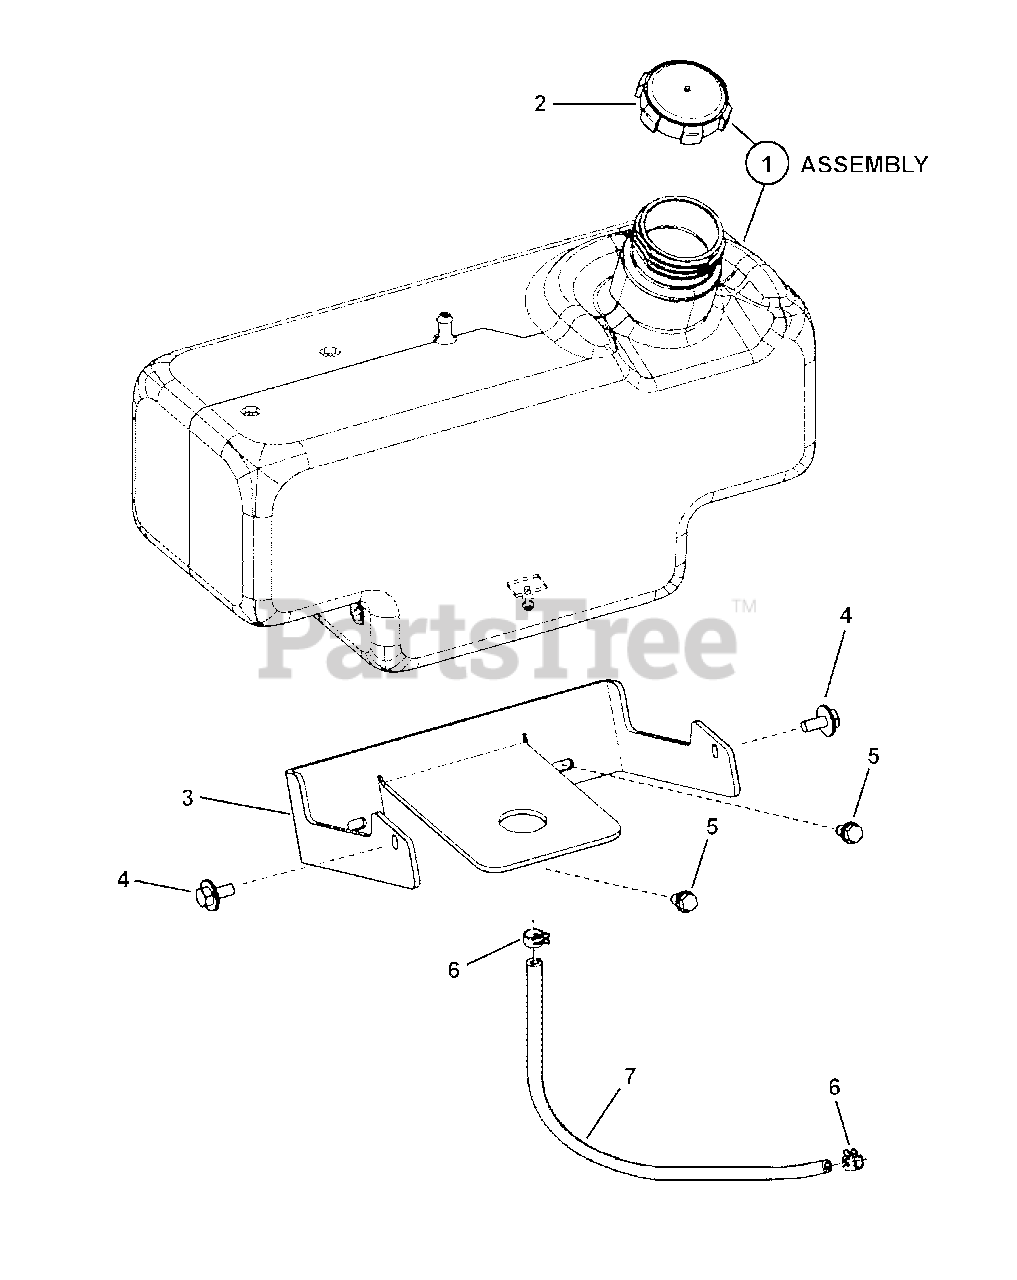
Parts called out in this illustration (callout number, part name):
1	FUEL TANK, Tractor w/Cap (Snapper)
2	FUEL CAP
3	BRACKET, Tank
4	SCREW, 1/4-20 x 5/8" Hex Washer Self-Tap
5	SCREW, 1/4-20 x 1/2" Hex Washer Self-Tap
6	HOSE CLAMP, Yellow
7	HOSE, Fuel, Low Perm, 1/4" I.D. x 17" long
